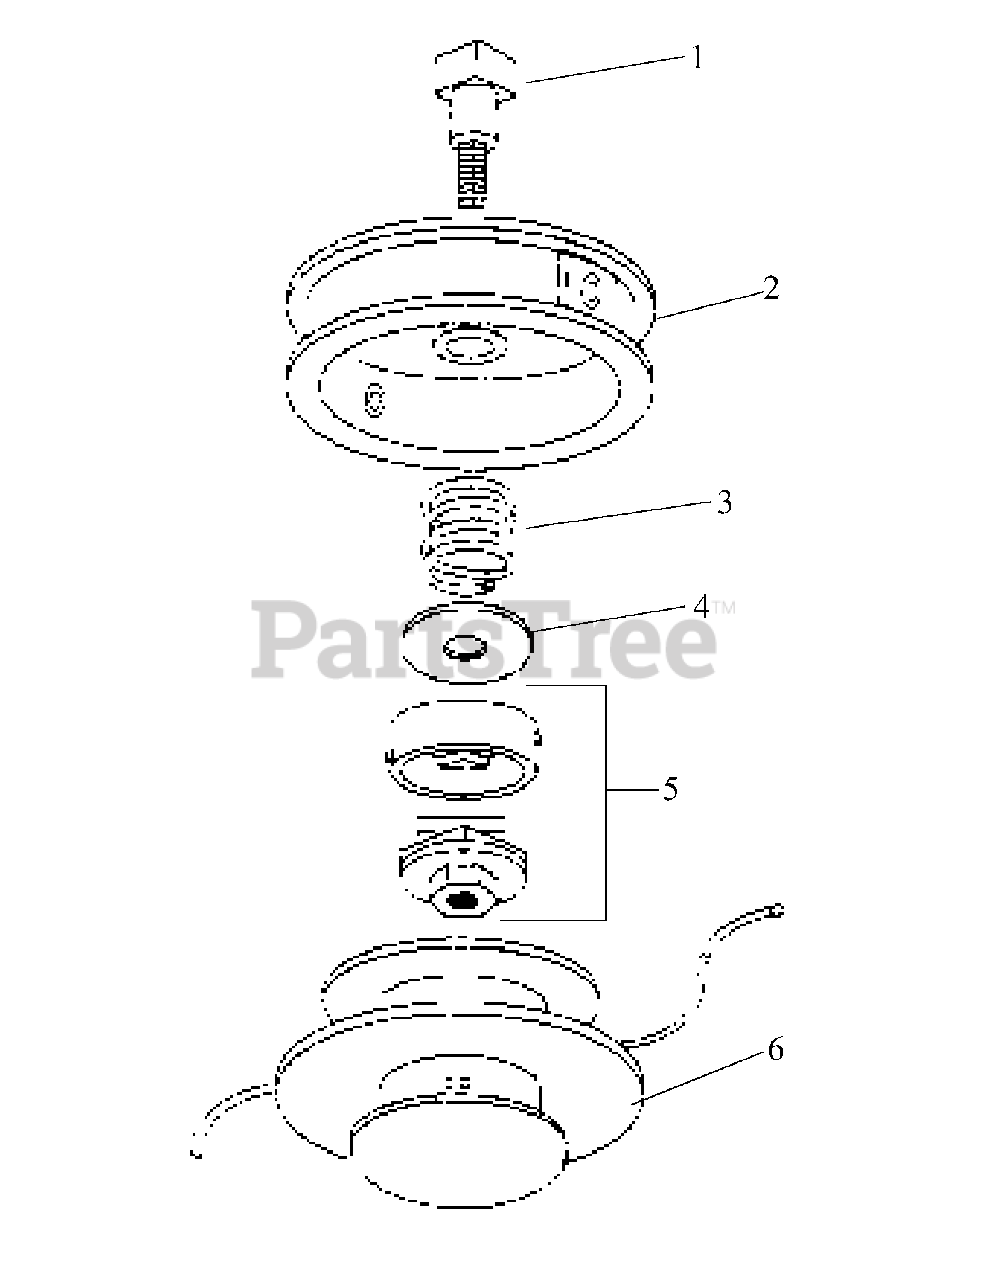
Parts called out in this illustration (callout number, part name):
1	Bolt, Shaft
2	Housing, Spool
3	Spring, Spool
4	Washer, Spring
